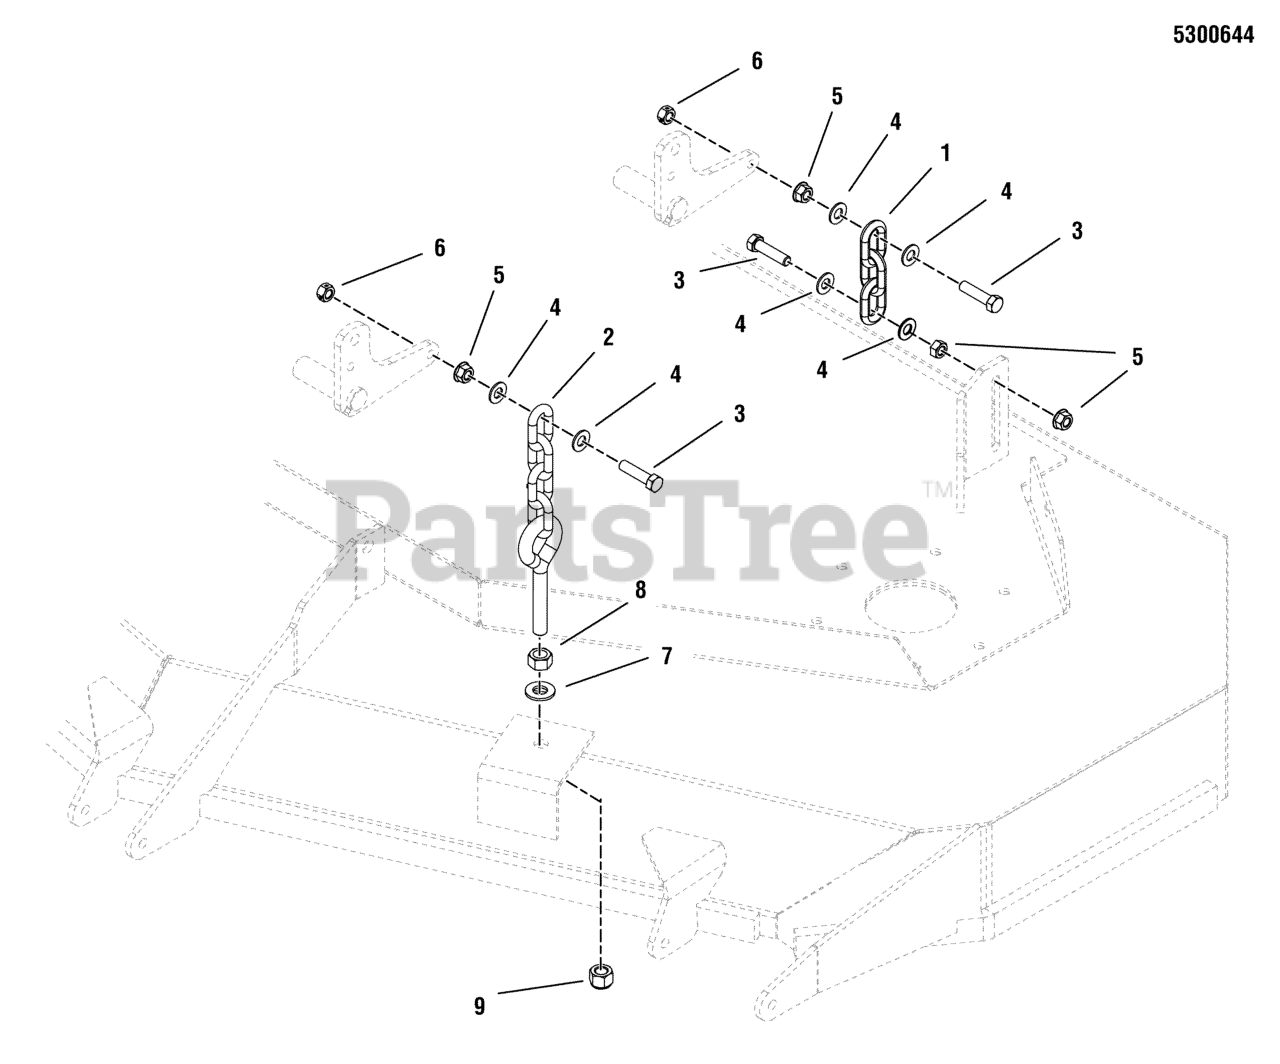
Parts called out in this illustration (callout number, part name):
1	CHAIN, 5/16 GD30, 3 LINKS
2	HANGER, FRONT DECK - 4 LINK, 5.5" EB
3	BOLT, 3/8-16 X 1-3/4" GD5 CZ
4	WASHER, 3/8 SAE
5	NUT, 3/8-16 HEX SERRATED FLANGE
6	NUT, 3/8-16 HEX SIDE LOCK
7	WASHER, 1/2 SAE
8	NUT, 1/2-13 HEX
9	NUT, Hex Flange, Nylock, 1/2-13
